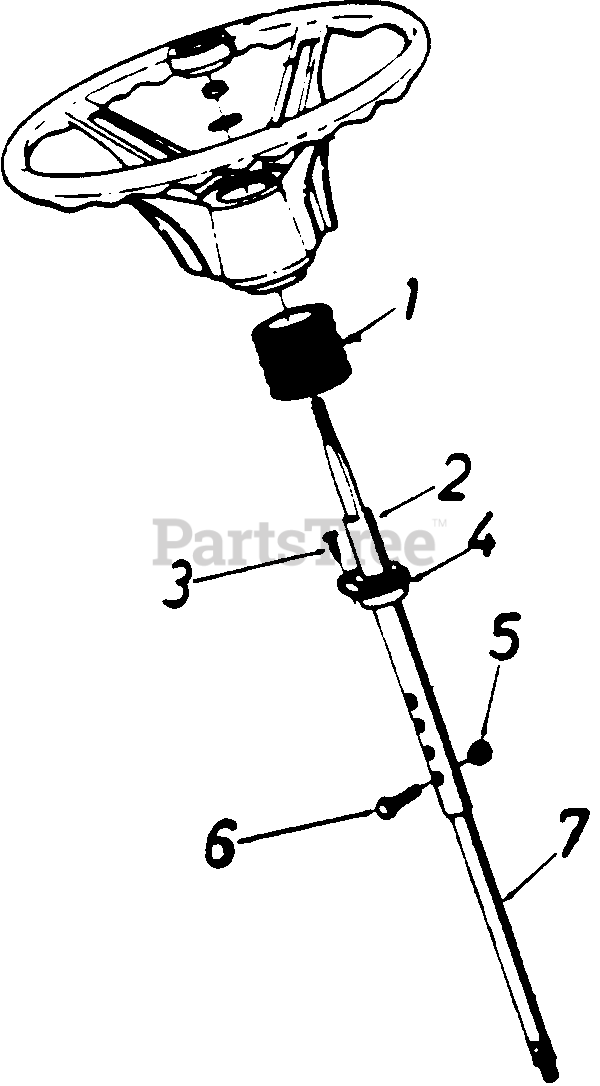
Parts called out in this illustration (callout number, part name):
1	Steering Bellow
2	Upper Steering Shaft
3	Oval Hd. C-Sunk Scr. #10 x 5/8" Lg.
4	Fl-Bearing .89" I.D. x 1.36" O.D.
5	Hex L-Nut 1/4-20 Thd.
6	Hex Bolt 1/4-20 x 1.31" Lg.
7	Lower Steering Shaft
